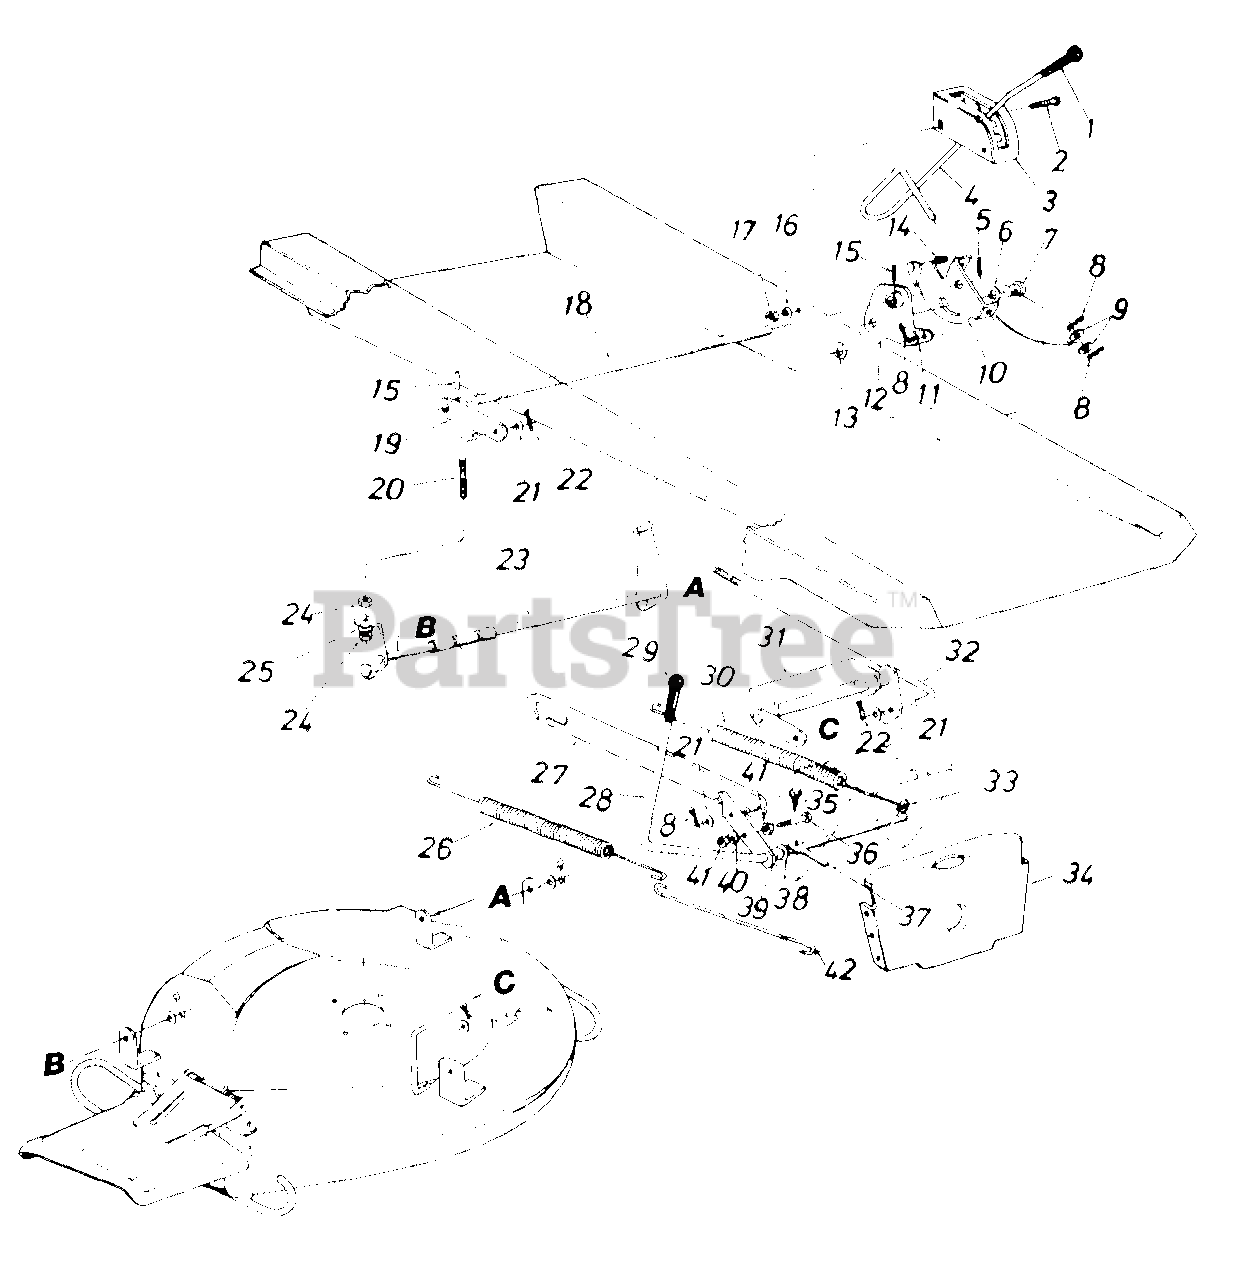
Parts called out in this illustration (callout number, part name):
2	Truss Mach. Scr. 5/16-18 x .75" Lg.*
5	Spring Pin Spir. 3/16" Dia. x 1.50" Lg.
6	Fl-Wash. .385" I.D. x .87" O.D.
7	Adj. Ferrule Deck Lift Handle
8	Cotter Pin 1/8" Dia. x 1.00" Lg.*
9	Fl-Wash. .531" I.D. x .930" O.D.
10	Deck Lift Handle Retainer Ass'y.
11	Fl-Wash. .385" I.D. x .87" O.D.
12	Deck Lift Brkt. Ass'y.-L.H.
13	Fl-Wash. .635" I.D. x 1.04" O.D.
14	Compression Spring .50" Dia. x 1.0" Lg.
15	Spring Pin Spir. 1/4" Dia. x 1.50" Lg.
16	L-Wash. 5/16" I.D.
17	Hex Nut 5/16-18 Thd.
18	Rear Hgt. Adj. Shaft
19	Deck Lift Brkt. Ass'y.-R.H.
20	Deck Adj. Scr. 3/8-16 Thd.
21	Fl-Wash. .385" I.D. x .87" O. D.
22	Intern. Cotter Pin 1/2" Dia.
23	Deck Link Ass'y.-Rear
24	Hex Nut 3/8-16 Thd.
25	L-Wash. 3/8" I.D.*
26	Extension Spring .73" O.D. x 13.84" Lg.
27	Deck Drive Control Bracket
28	Blade Engagement Lever Ass'y.
30	Extension Spring .73" O.D. x 13.89" Lg.
31	Deck Lift Ass'y.-Front
32	Deck Lift Connecting Rod
33	Clevis Pin Special .250" Dia.
34	Pivot Bar Bracket
35	Hex TT-Tap Scr. 1/4-20 x .75" Lg.
36	Hex Bolt 5/16-18 x 1.50" Lg. (Grade 5)
37	Switch Actuator
38	Fl-Wash. .531" I.D. x .930" O.D.
39	Spacer .511" I.D. x .70" O.D. x.38" Lg.
40	L-Wash. 5/16" I.D.
41	Hex Nut 5/16-18 Thd.
42	Spring Hook
